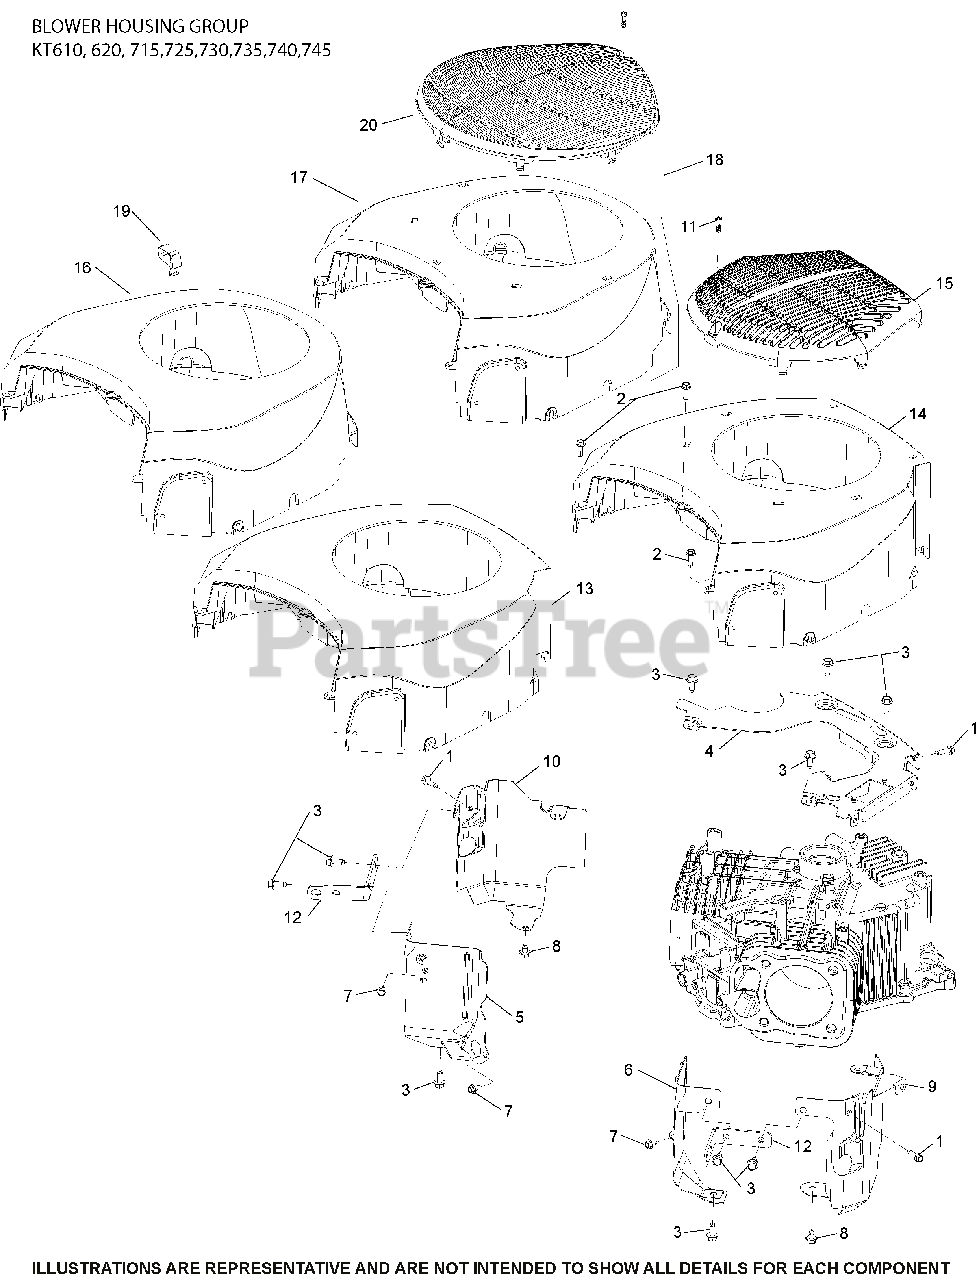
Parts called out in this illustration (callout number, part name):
1	SCREW, THREAD FORMING - USE 25 086 473-S
2	SCREW, HI-LOW
3	SCREW, THREAD FORMING
4	PLATE, BACKING
5	BAFFLE, VALLEY #1 USE 32 063 23-S
6	BAFFLE, VALLEY #2
7	SCREW, THREAD FORMING
9	BAFFLE, LEFT BARREL
10	BAFFLE, RIGHT BARREL
11	SCREW, M5-2.42 (PT) THREAD
12	STRAP, LIFTING
14	HOUSING, BLOWER USE 32 027 20-S
15	GUARD, FIXED
